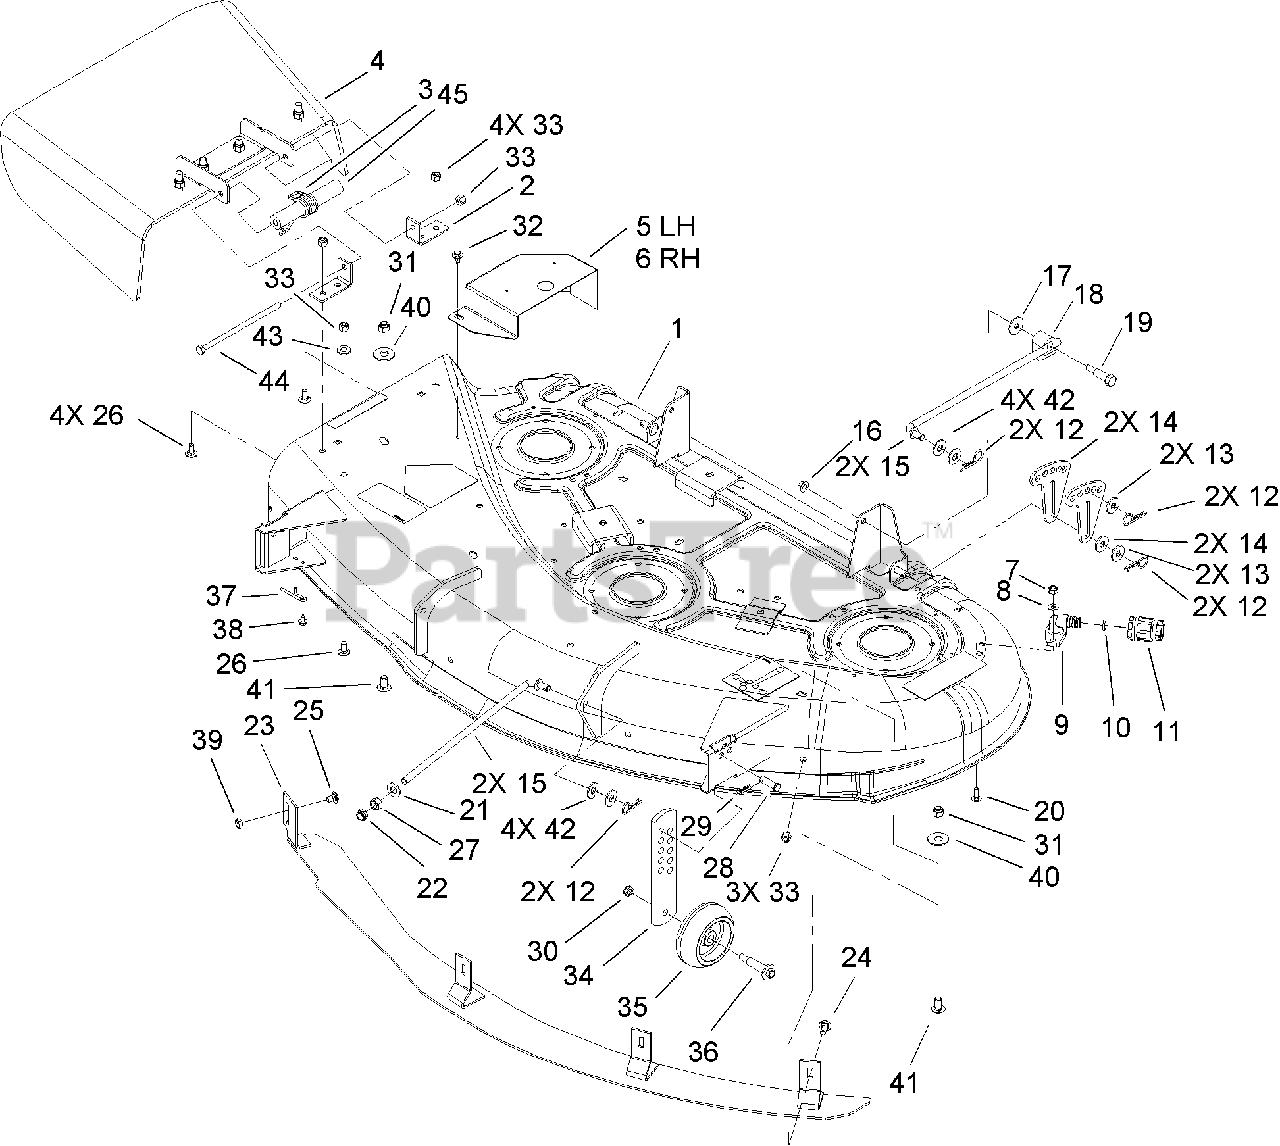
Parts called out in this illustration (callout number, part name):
1	44 INCH DECK ASM
2	BRACKET-PIVOT, DEFLECTOR
3	SPRING-TORSION
4	DEFLECTOR ASM
6	COVER-BELT, RH
7	NUT-LOCK, NI
8	WASHER-FLAT
9	FITTING-WASHOUT
11	CONNECTOR-HOSE
12	PIN-HAIR
13	WASHER-HARDENED
14	LINK-ADJUSTING, HOC
15	ROD-HANGER
17	WASHER-PIVOT
18	TRUNNION-HOC
19	BOLT-SHOULDER
20	SCREW-CARR
21	WASHER-FLAT
22	NUT-LOCK, NI
24	BOLT-CARR
25	SCREW-CARR
26	SCREW-CARR
27	NUT-HEX
28	PIN-CLEVIS
29	PIN-HAIR
30	NUT-LOCK, NI
31	NUT-LOCK, NI
32	SCREW-HHF
33	NUT-LOCK, NI
34	PLATE-GAGE, WHEEL
35	WHEEL-GAGE
36	BOLT-WHEEL
37	SPRING-GAGE, WHEEL
39	NUT-LOCK, NI
40	WASHER-FLAT
41	SCREW-CARR
42	WASHER-FLAT
43	WASHER-FLAT
45	SPACER-DEFLECTOR
